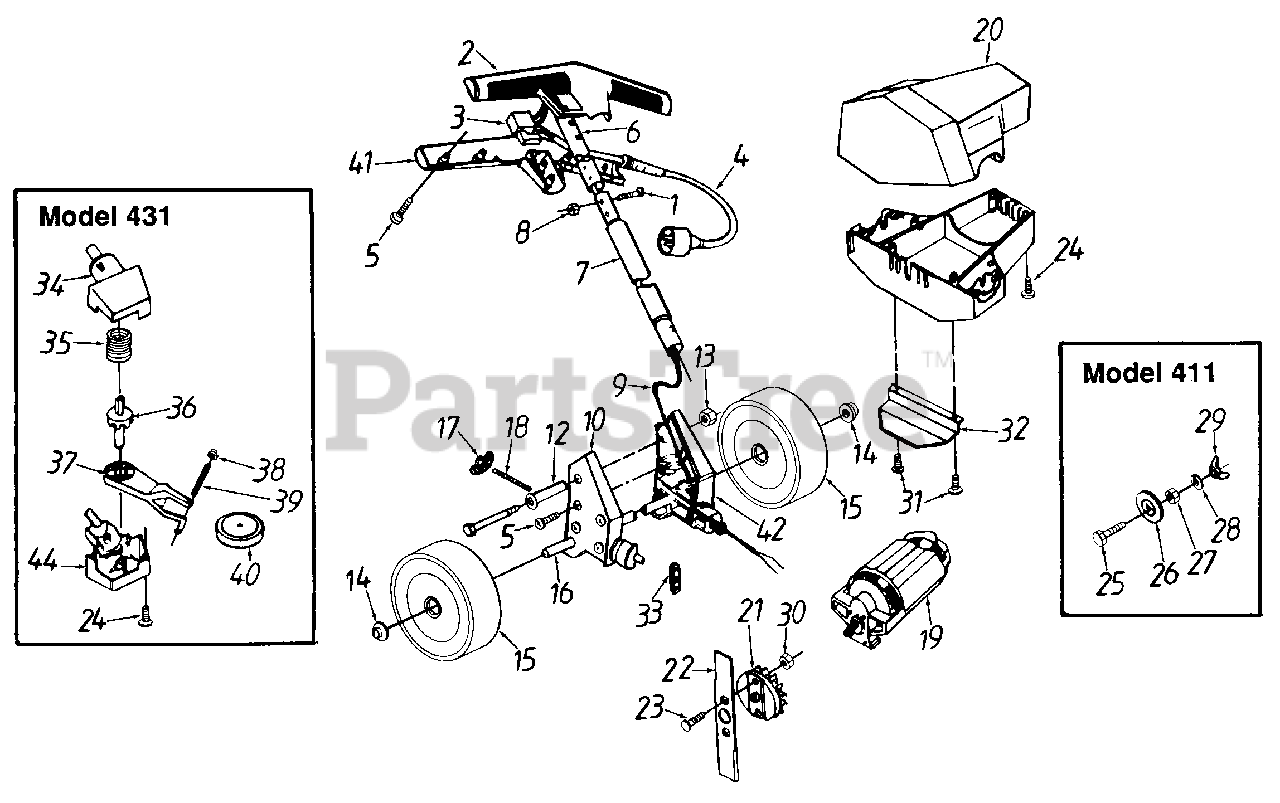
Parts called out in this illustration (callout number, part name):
1	Scr. #10-24 x 11/4" Lg.
2	T-Handle-Lower
3	Switch
4	Cord Set (2 Prong)
5	Scr. #8 x 5/8" Lg.
6	Upper Tube
7	Lower Tube
8	Hex Nut #10-24 Thd.
9	Wire Harness
10	Rear Support-R.H.
12	Sleeve
13	Hex L-Nut 5/16-18 Thd.
14	Push Nut 3/8n
15	Rear Wheel
16	Rear Axle
17	Plastic Wing Nut
18	Threaded Rod
19	Motor Ass y.
20	Motor Hsg.-Upper
21	Adapter
22	Blade
23	Hex Bolt (Grade 5)
24	Screw #8 x 1" Lg.
25	Hex Bolt 1/4-20 x 1.5"
26	Guide Wheel
27	Hex Nut 1/4-20 Thd.
28	L-Wash. 1/4" I.D.
29	Wing Nut 1/4-20 Thd.
30	Hex L-Nut 1/4-20 Thd.
31	Scr. #8 x 2.75" Lg.
32	Edge Guide
33	Flange Nut
34	Front Support-L.H.
35	Spring
36	Shaft-Release Button
37	Fork-Front Wheel
38	Push Nut 1/4"
39	Axle-Front Wheel
40	Front Wheel
41	T-Handle-Upper
42	Rear Support-L.H.
44	Front Support-R.H.
